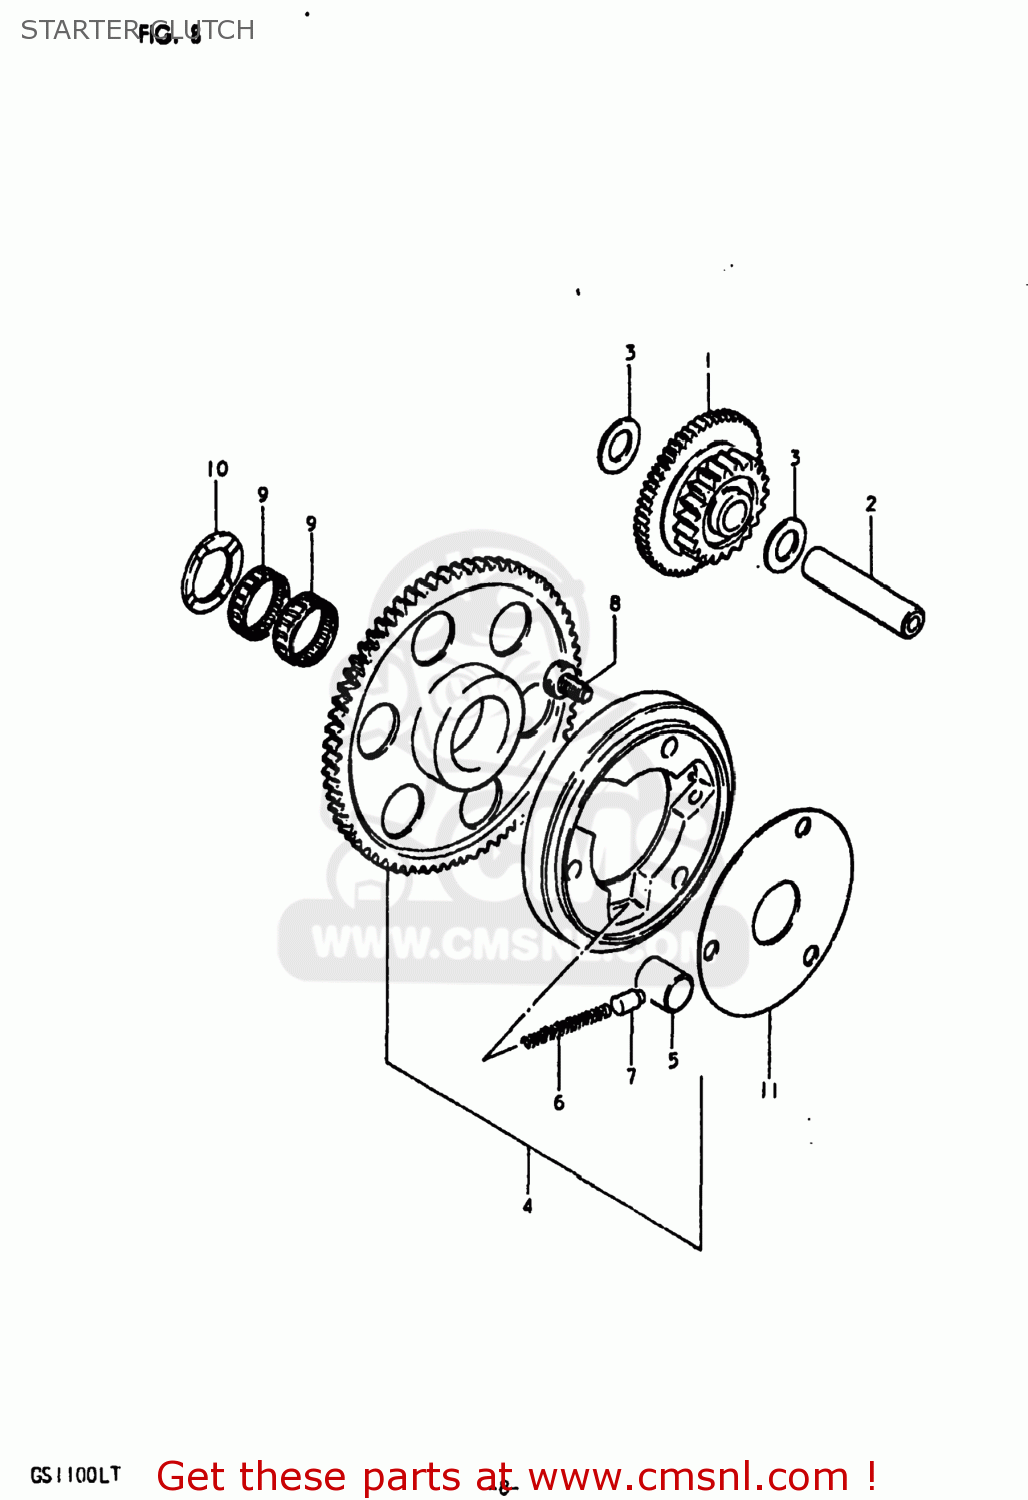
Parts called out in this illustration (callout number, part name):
1	GEAR,STARTER IDLE
2	PIN(7.4X13X56)
3	WASHER(13.3X25X0.85)
4	CLUTCH SET,STARTER
5	ROLLER(15X13)
6	SPRING
7	PIECE,PUSH
8	BOLT
9	BEARING
10	WASHER(25X38X2.5)
11	SHIM,STARTER CLUTCH HUB
